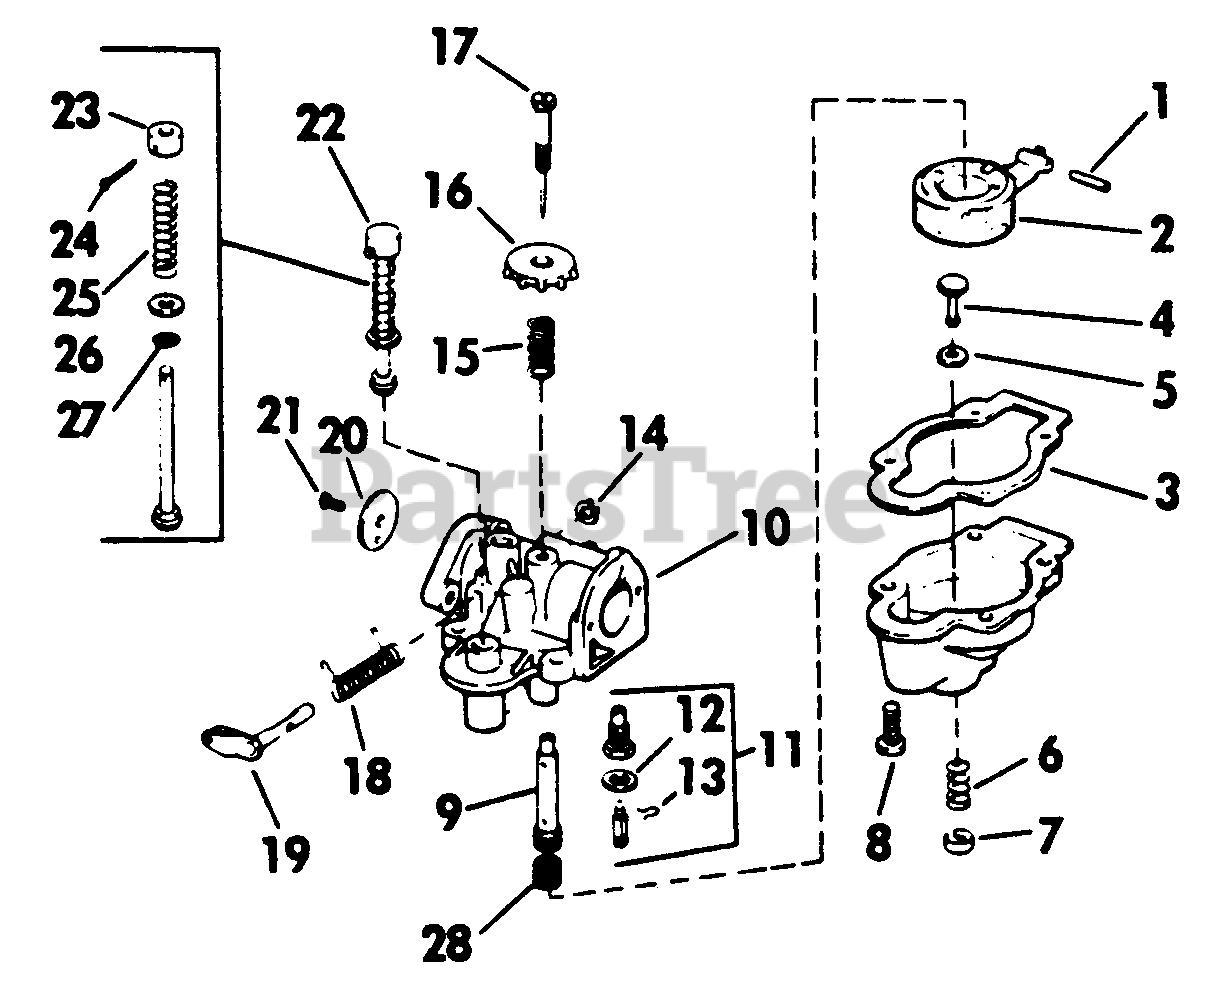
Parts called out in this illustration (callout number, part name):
1	Pin-Float Arm Hinge
2	Float and Arm Assy.
3	Gasket-Float Chamber
4	Valve Stem
5	Valve Seat
6	Valve Spring
7	Valve Keeper
8	Screw-Float Chamber
9	Nozzle
10	Carburetor Body Assy.
11	Float Valve & Seat
12	Washer-Float Valve Seat
13	Clip
14	Grip Ring
15	Spring-Needle Adj.
16	Knob-Needle Adj.
17	Needle Assy.
18	Spring-Throttle
19	Throttle Shaft & Lever Assy.
20	Disc-Throttle
21	Screw-Throttle Shaft Disc
22	Primer Assy.
23	Knob Primer
24	Cotter Pin
25	Spring Compression
26	Washer-Plain
27	"O" Ring
